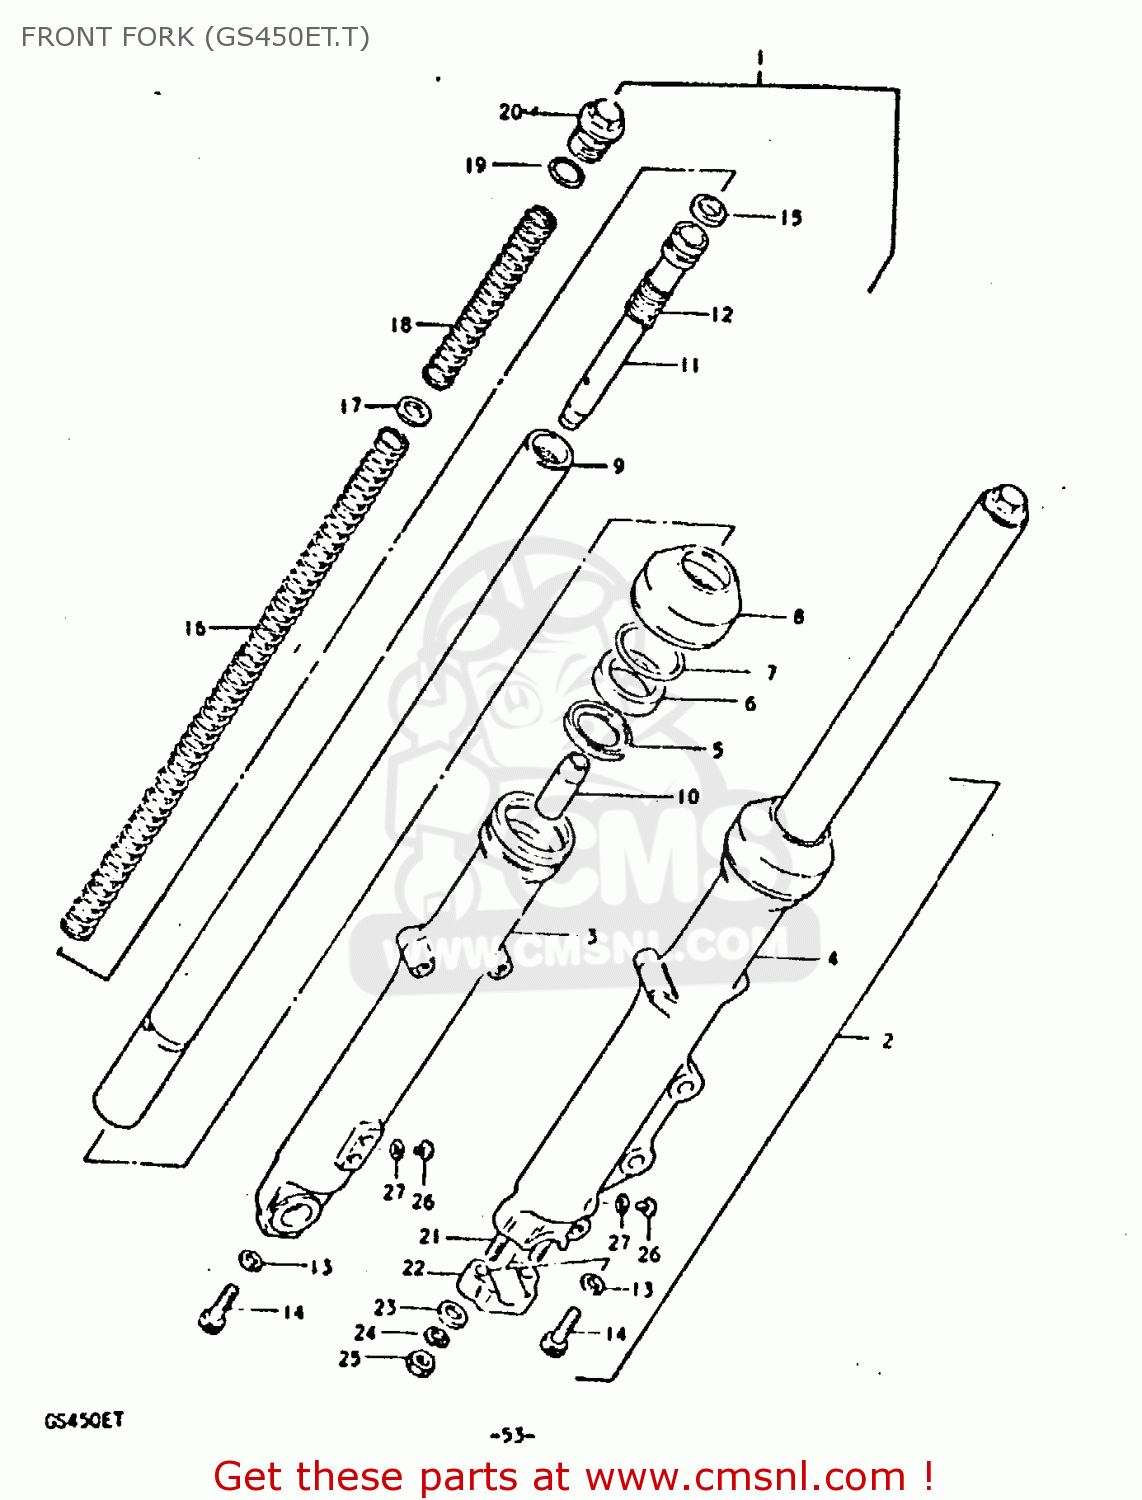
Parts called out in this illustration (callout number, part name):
1	DUMPER ASSY, RH
2	DUMPER ASSY, LH
3	TUBE,FORK,OUTER,RIGHT
4	TUBE,FORK,LEFT,OUTER
5	SPACER,OIL SEAL
6	OIL SEAL,FRONT FORK
7	CIRCLIP,FORK OIL SEAL
8	BOOT
9	TUBE,INNER
10	PIECE,OIL LOCK
11	PIPE, SEAT
12	SPRING,REBOUND
13	GASKET (NAS)
14	BOLT(8X27)
15	RING,PISTON
16	SPRING
17	SEAT,SPRING
18	SPRING,FRONT FORK
19	O RING
20	BOLT
21	STUD 8X25
22	HOLDER,AXLE
23	WASHER
24	LOCK WASHER
25	NUT (8MM)
26	SCREW 4X6
27	GASKET (NAS)
